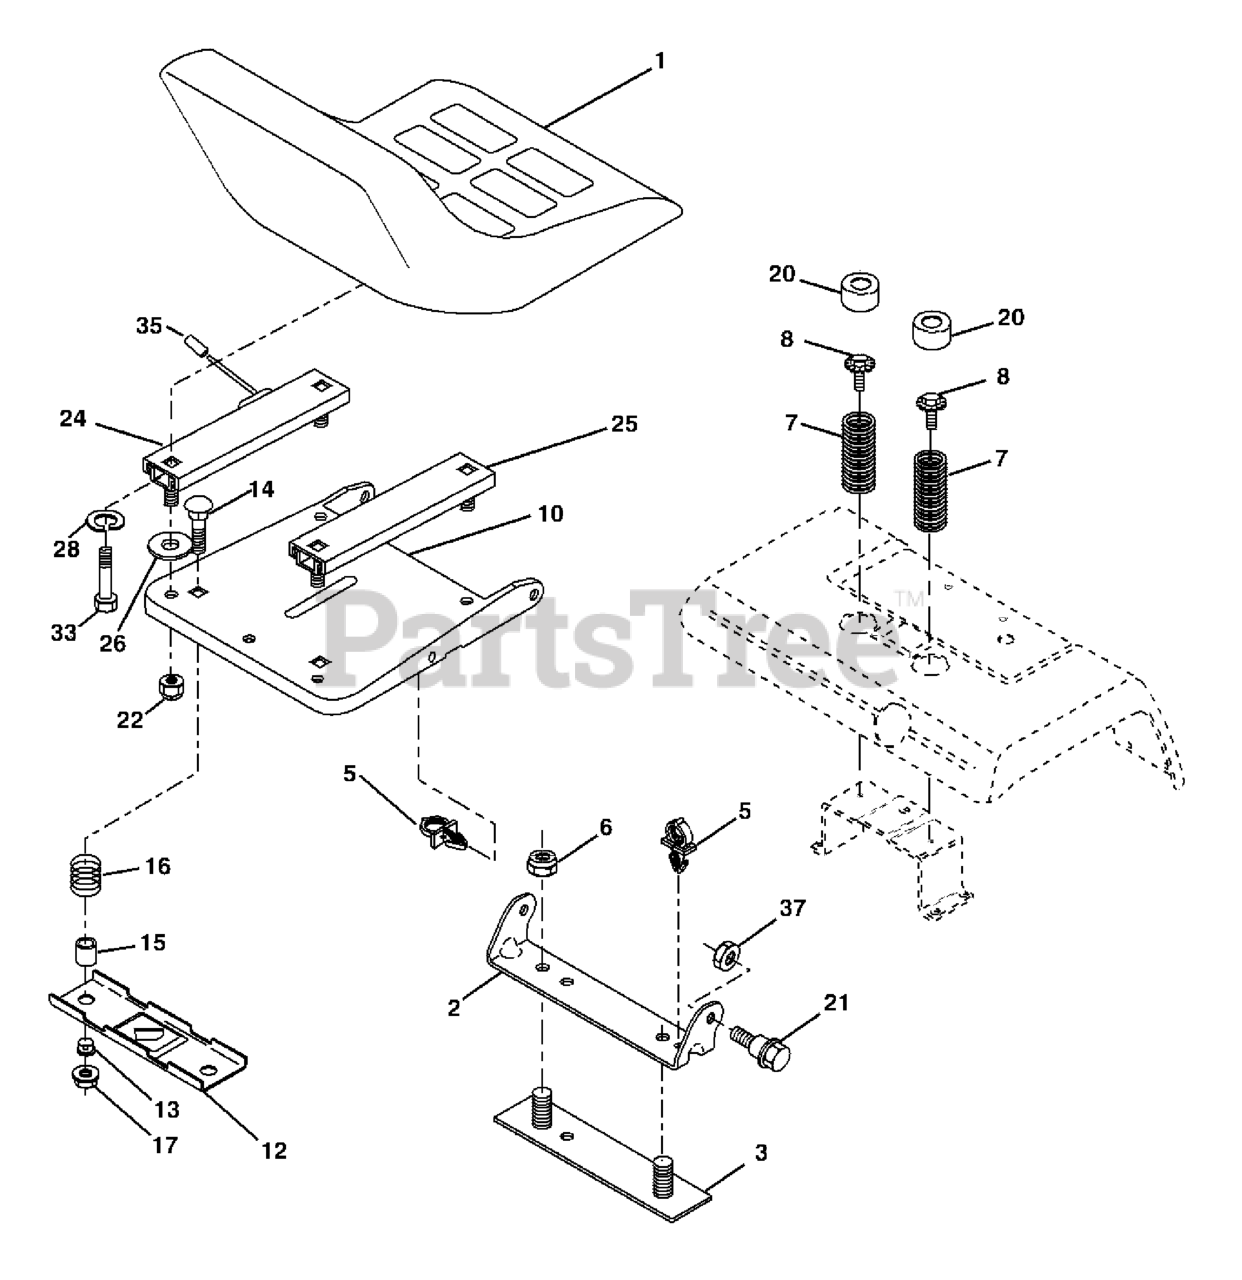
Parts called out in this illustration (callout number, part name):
1	SEAT.XH150.GRY
2	SEAT PIVOT BRKT
3	STRAP
6	NUT
7	SPRING COMPRESSION
8	BOLT.5/16-18UNCX3/4 W/SEMS.BLK
10	PAN SEAT
12	BRKT.MNTNG.SWITCH.SEAT.BLACK
14	BOLT.ROUND.HEAD.SQUARE.NECK
15	SPACER SPLIT
16	SPRING COMPRESSED
17	NUT T
20	CAP SPRING
21	BOLT.SHOULDER.5/16-18
22	LOCKNUT
24	TRACK SLIDE, SEAT(L)
25	TRACK SLIDE, SEAT(R)
26	WASHER T
33	BOLT.FIN.HEX.5/16-18X3/4
35	CAP
37	NUT.71038.31-18.HEX.NYLOCK
